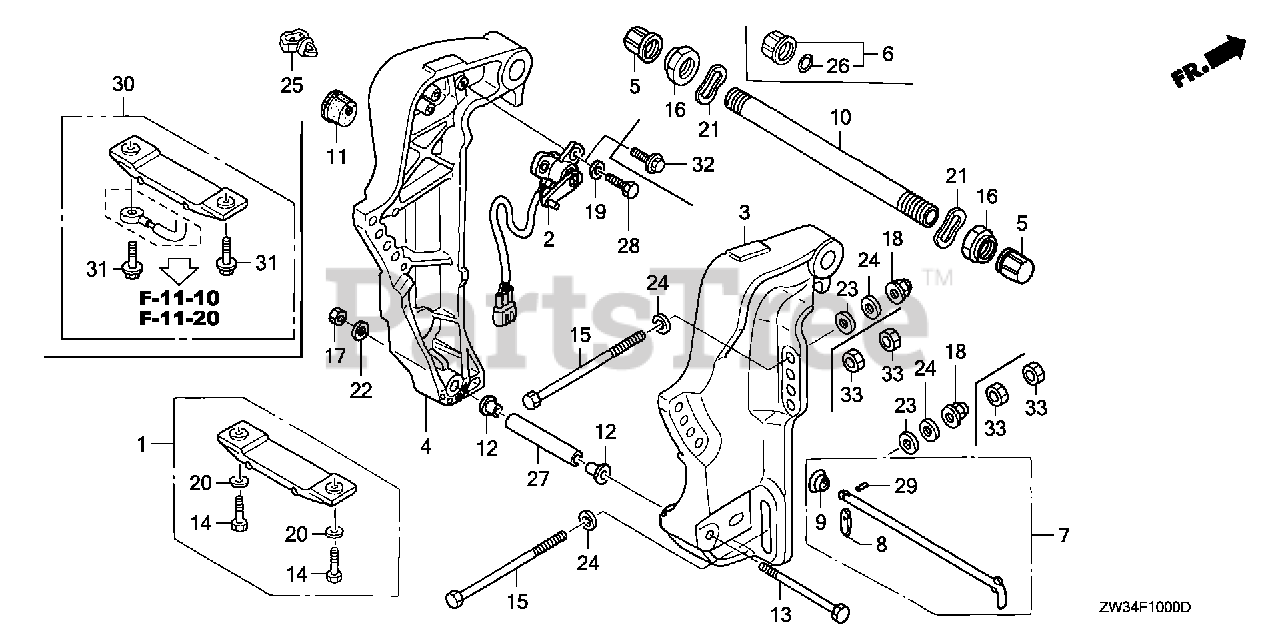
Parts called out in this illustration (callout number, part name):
2	SENSOR ASSY., TRIM ANGLE
3	BRACKET, R. STERN *NH282MU* (OYSTER SILVER METALLIC-U)
4	BRACKET, L. STERN *NH282MU* (OYSTER SILVER METALLIC-U)
5	CAP, TILTING BOLT
7	ROD, ADJUSTING
8	STOPPER, ROD
9	SPRING, ADJUSTING ROD
10	SHAFT, TILTING
11	BUSH, MOTOR CODE
12	BUSH, CYLINDER (LOWER)
13	BOLT, HEX. (10X158)
15	BOLT, HEX. (12X100)
16	NUT, SELF-LOCK (7/8-14UNF)
17	NUT, SELF-LOCK (10MM)
18	NUT, SELF-LOCK (12MM)
21	WASHER, WAVE (22MM)
22	WASHER, PLAIN (10MM)
23	WASHER, PLAIN (12MM)
24	WASHER, PLAIN (12MM)
25	CLIP, WIRE HARNESS
26	O-RING (15.54X2.62)
27	COLLAR, DISTANCE (10X90)
29	PIN, SPRING (2.5X8)
30	METAL KIT, ANODE
31	BOLT, FLANGE (6X23)
32	BOLT, FLANGE (6X20)
